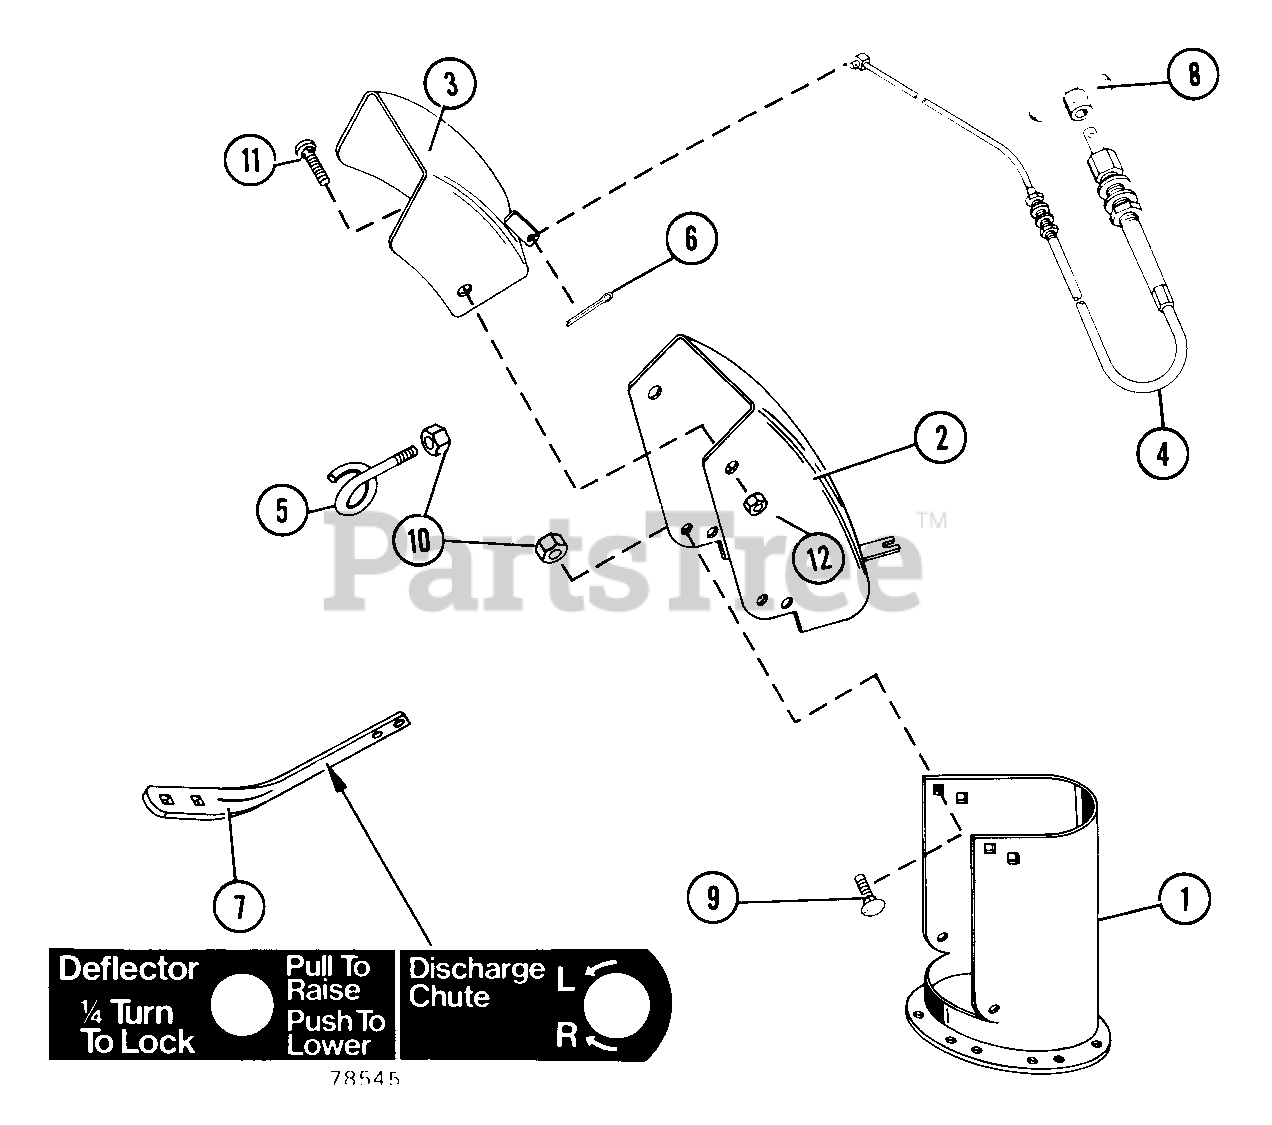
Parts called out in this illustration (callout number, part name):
1	DISCHARGE CHUTE
2	CHUTE
3	CHUTE DEFLECTOR
4	CHUTE CONTROL
5	BLT-HEX .50-13X3.00 PL GR2
6	PIN-COTR .09X.75 PL
7	CABLE SUPPORT
8	T-HANDLE
9	BLT-RDHDSQNK .25-20X.62 PL
10	NUT-LK-FLG .250-20 PL
11	BLT-HEX .38-16X.75 PL GR2
12	NUT-LK-CTR .375-16 GR A PL
